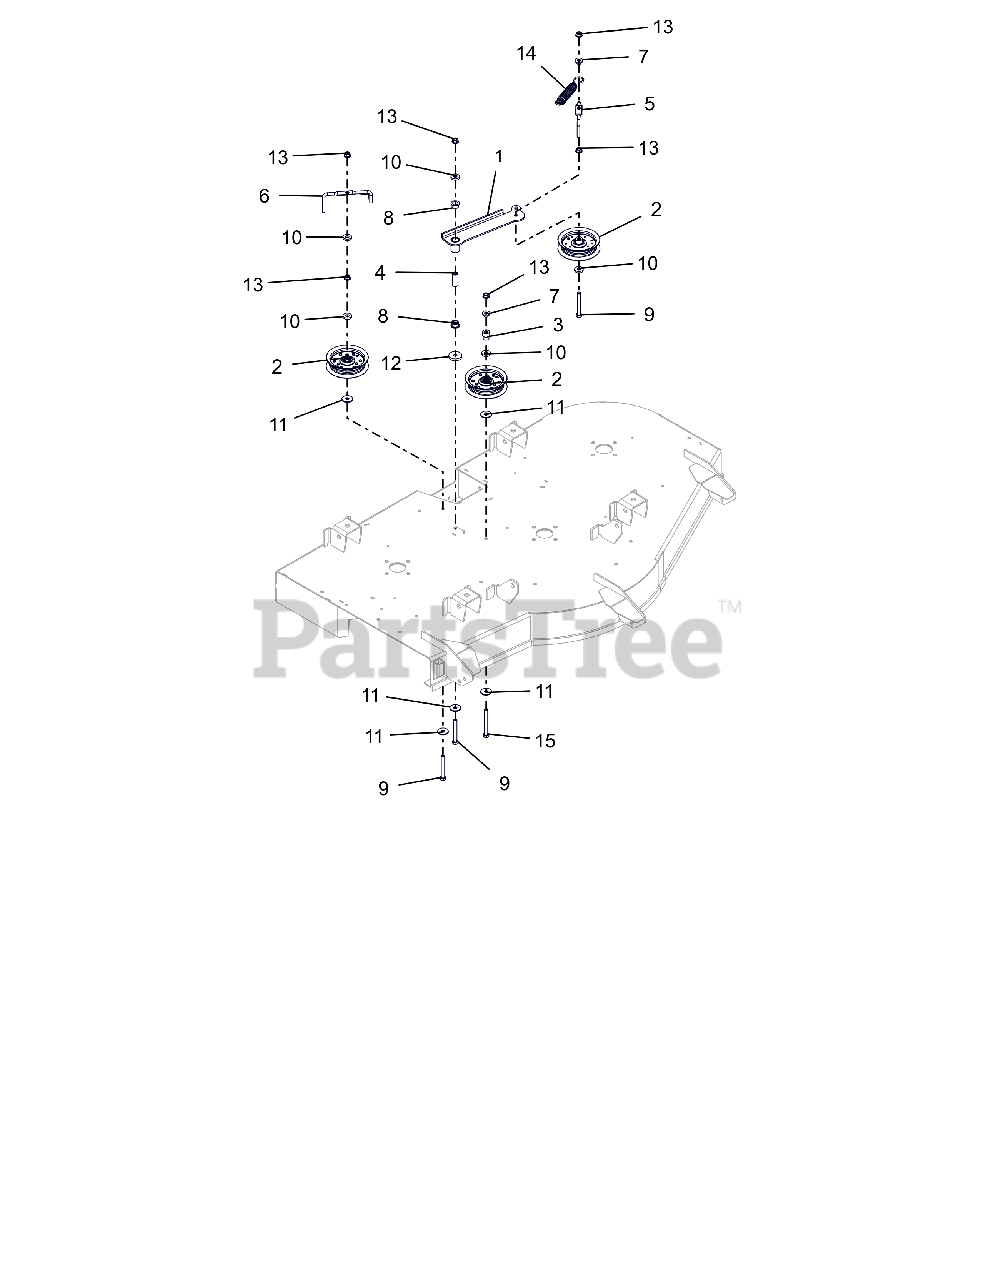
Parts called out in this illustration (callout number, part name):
1	WLDMT, IDLER ARM-52"
2	ASM, IDLER 4"
3	BUSHING, IDLER (P/M)
4	SPACER, .375IDX.625ODX1.66 PM
5	WIREFORM, BELT FINGER
6	WIREFORM, BELT FINGER
7	BSHG-FLG .385X.500X.875X.406
8	BSHG-FLG, .625X.750X.500X1.00
9	BLT, HEX .38-16X3.00F G5 ZCC
10	WSHR, FLT .406X1.00X.188 ZCC
11	WSHR FL STL .406X1.25X.10ZC120
12	WSHR, FLT .406X1.50X.245 ZCC
13	NUT-LK-TOP-FLG .38-16 ZC120
14	SG-TENS .135X.98X6.0 WLD 62
15	BLT, HEX .38-16X3.50 G5 ZCC
